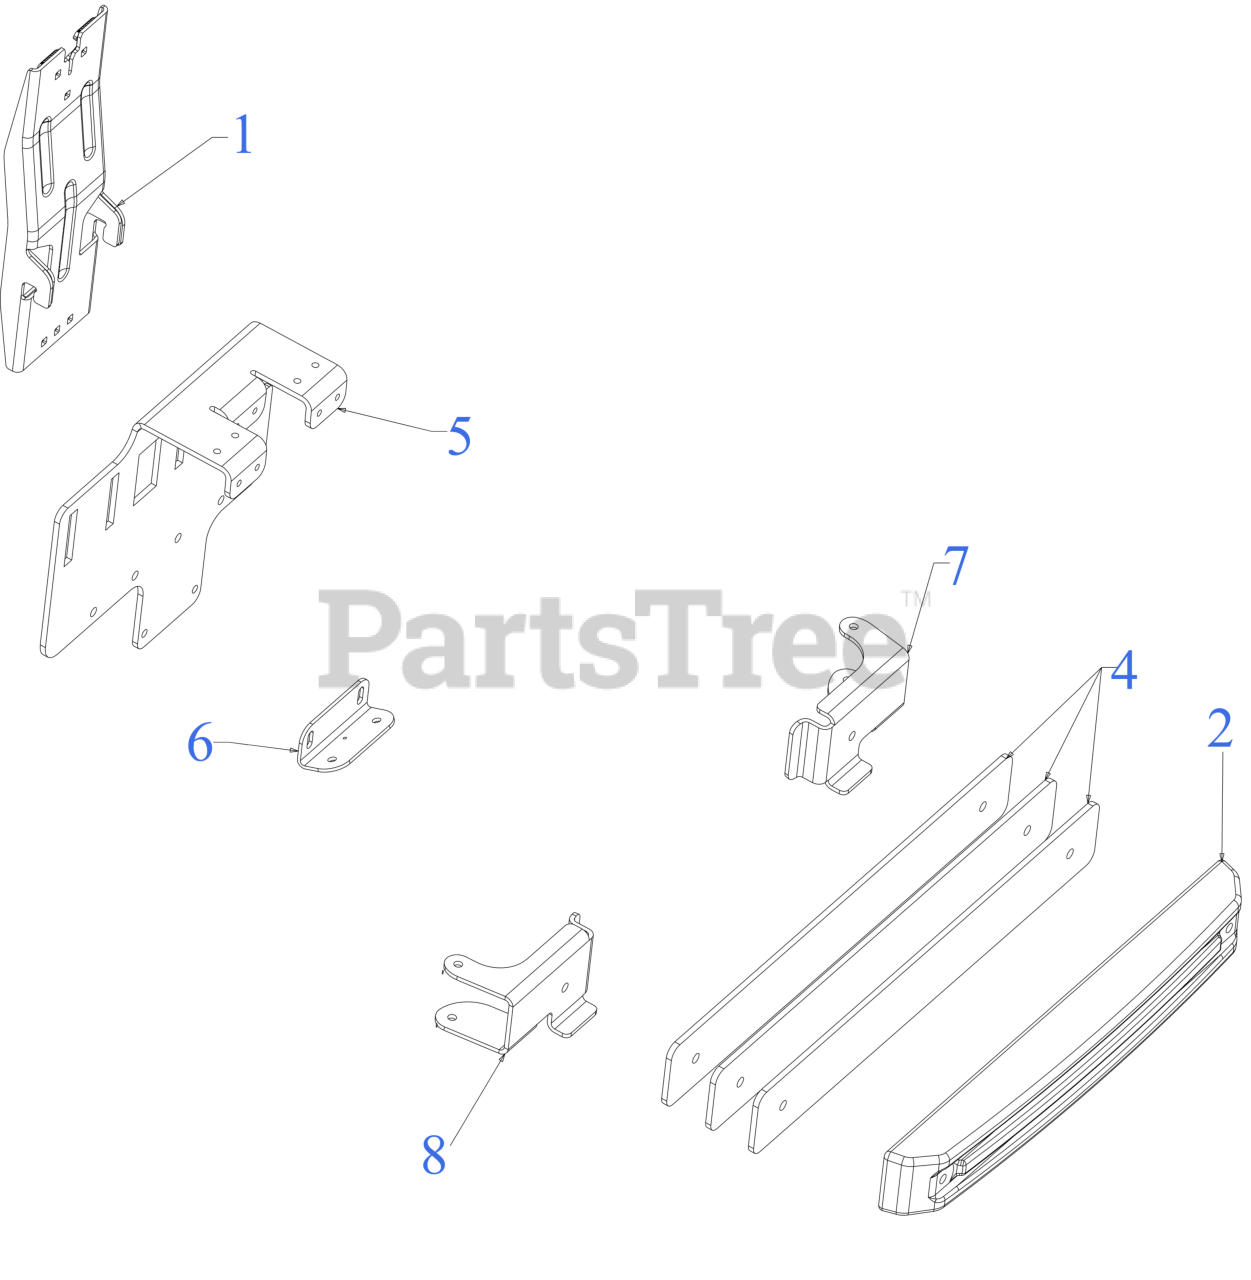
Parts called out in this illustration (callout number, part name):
1	VERTICAL SUPPORT BRACKET
2	BAGGER WEIGHT
4	WEIGHT PLATE
5	ADAPTER BRACKET
6	HITCH ADAPTER BRACKET
7	WEIGHT HANGER BRACKET (LH)
8	WEIGHT HANGER BRACKET (RH)
